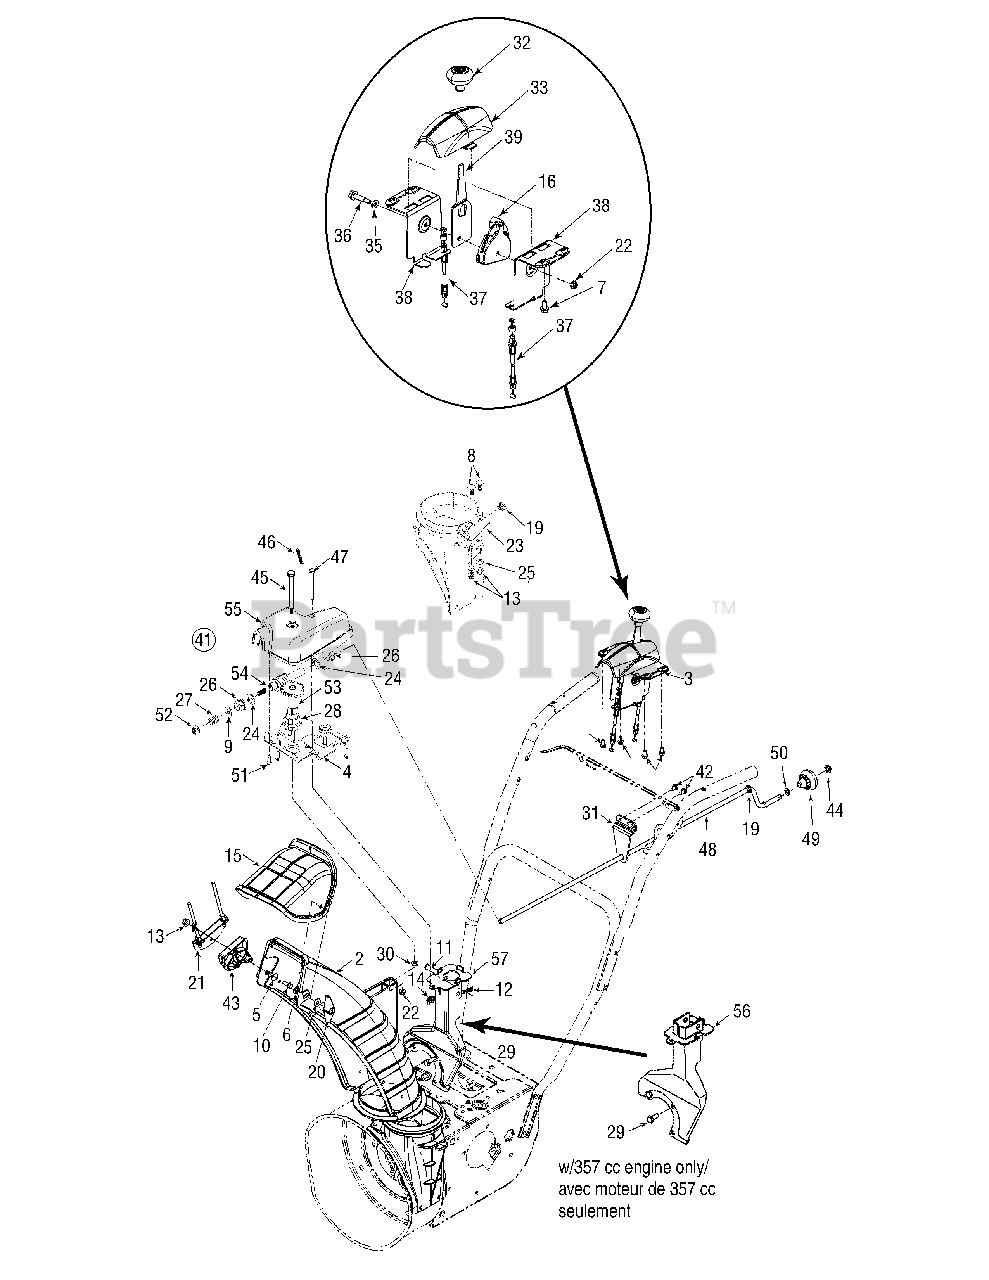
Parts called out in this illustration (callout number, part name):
2	Tall Lower Chute
3	2 Way Chute Control Assembly
4	Chute Gear Rotation Bracket
5	Carriage Bolt 5/16-18 x 1.50 Gr. 2
6	Carriage Screw 5/16-18 x 1.0
7	Hi-Lo Screw 1/4-15 x .5
8	Carriage Bolt 5/16-18 x 1.00" Lg
9	Flat Washer .385 x .87 x .06
10	Hex Tapp Scr 1/4 x .75" Lg.
11	Clevis Pin 3/8 x 1.87
12	Bow Tie Cotter Pin
13	Flange Locknut 5/16-18 Gr. F Nylon
14	Wing Nut 1/4-20
15	Upper Chute w/Export Label, Remote
19	plastic Bushing .380 ID
20	Handle Knob Assembly
21	Cable Bracket Chute Tilt
22	Hex L-Flanged Nut 1/4-20 Gr. F Nylon
23	Chute Crank Brkt.
24	Flat Washer .625 x 1.0 x .067
25	Flat Washer .349 ID x .879 OD x .063
26	Hex Flg. Bearing
27	Compression Spring .39 x .60 x .88
29	Hex Hd. Cap Screw 5/16-24 x .75
30	Flat Washer .25 ID x .63 OD x .0515 HT.
31	Support Rod Bracket
33	Control Cover - 2 Way
35	Spring Washer .390 x .625 x .012
36	Flg Shlder Screw .310 x .995: 1/4-20
37	Cable - w/tall chute
38	Mounting Bracket - 2 Way
41	Gearbox Assembly
42	Hex Wash Hd TT Scr. 1/4-20 x .625
44	Push Nut 3/8" Rod
45	Flg. Shoulder Screw .312 x 3.5: 1/4-20
46	Internal Cotter Pin
47	Hex. Hd. Cap Scr. 1/4-20 x 3.0 Gr. 5
48	Chute Crank .375 Dia. x 30.5" Lg.
50	Flat Washer .375 x .738 x .063
51	Hi-Lo Screw #12-16 x .75
52	Hex L-Flanged Nut 3/8-16 Gr. F Nylon
53	Gear 23 teeth helical w/hub
56	Chute Sup. Bkt. Ass'y (w/357 cc engine only)
57	Chute Support Bracket Ass'y
